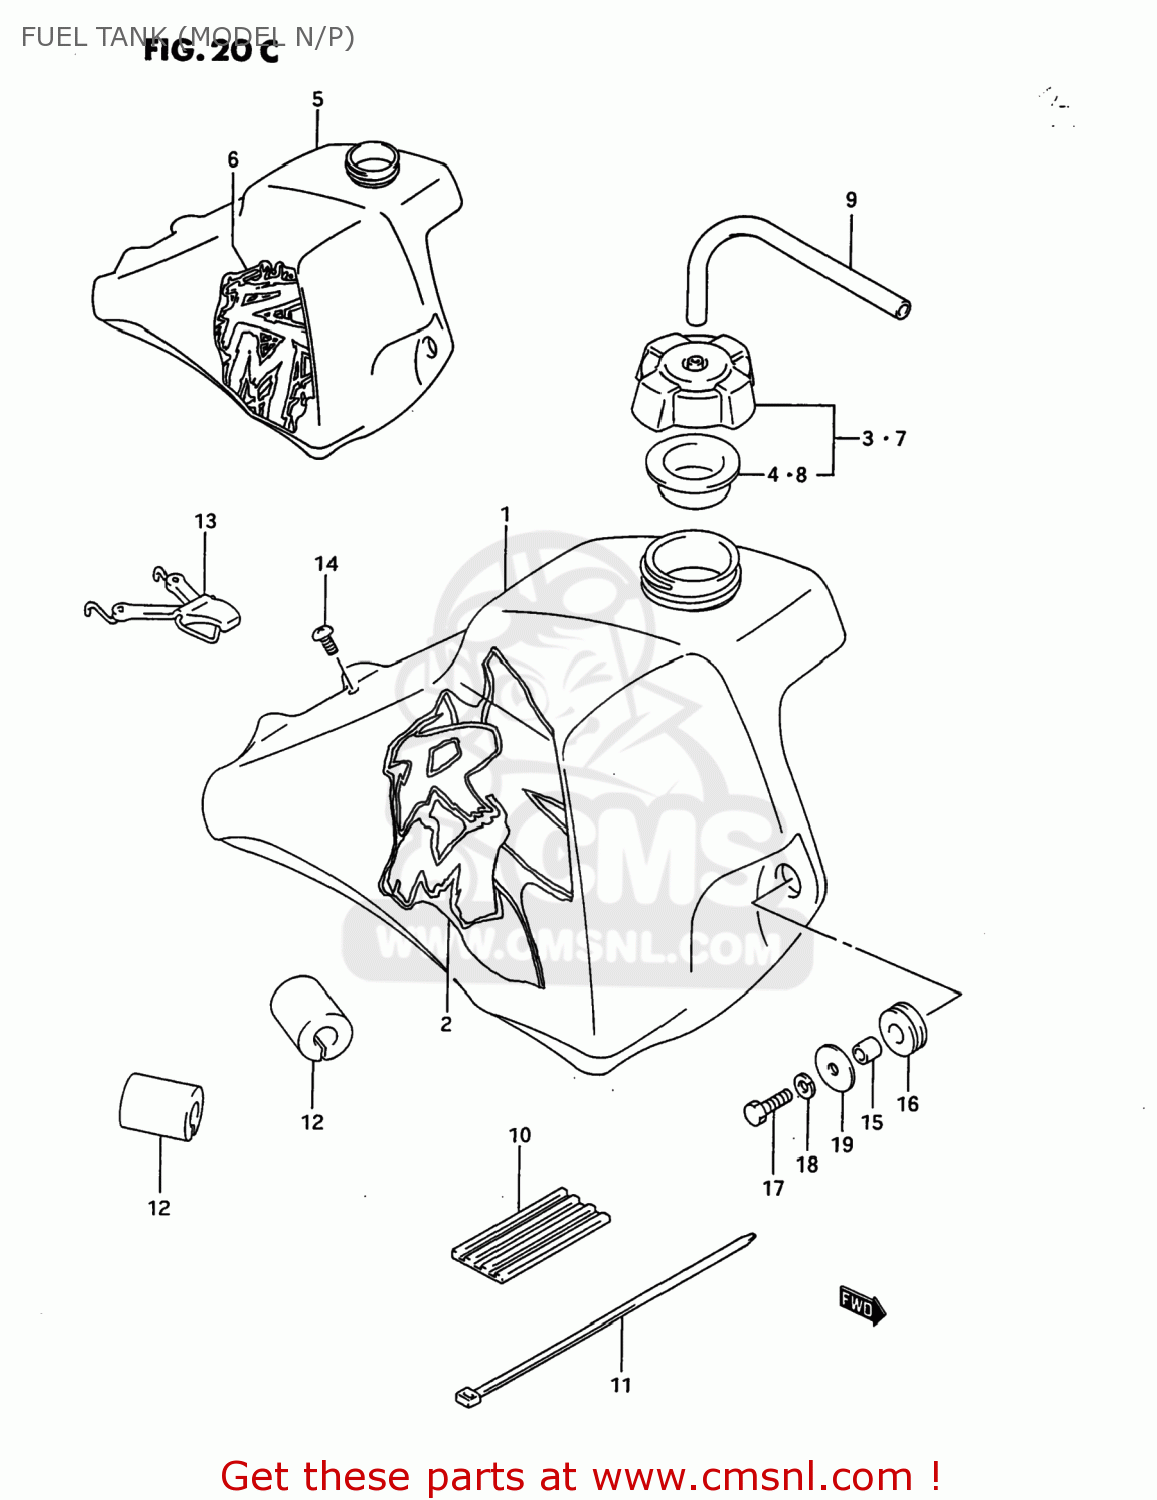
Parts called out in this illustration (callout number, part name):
1	TANK SET,FUEL
2	EMBLEM,FUEL TANK
3	CAP SET,FUEL TANK
4	GASKET,FUEL TANK CAP (NAS)
5	TANK ASSEMBLY,FUEL
6	EMBLEM,FUEL TANK
7	CAP SET,FUEL TANK
8	GASKET,FUEL TANK CAP (NAS)
9	HOSE
10	CUSHION,FUEL TANK UPR FR
11	CLAMP
12	CUSHION,FUEL TANK UPR RR
13	BAND,FUEL TANK RR
14	SCREW
15	SPACER (6.8X10X11.5)
16	CUSHION
17	BOLT
18	WASHER,LOCK
19	WASHER (6.5X24X1.6)
